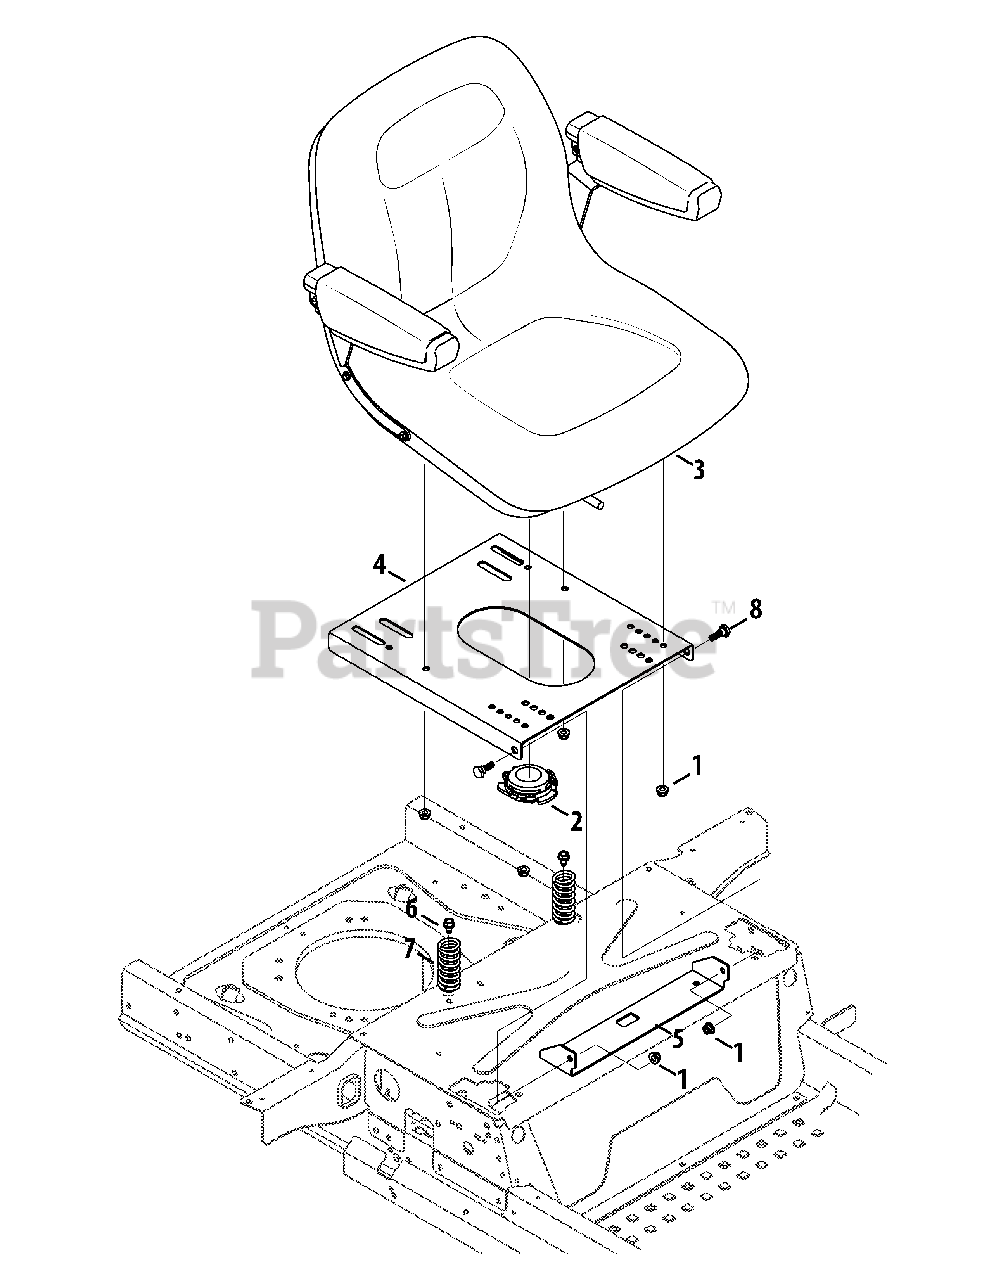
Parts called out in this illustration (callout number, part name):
1	Flange Lock Nut, 5/16-18
2	Seat Switch
4	Seat Plate
6	Hex Washer Screw, 5/16-18 x .750
7	Compression Spring, 1.71 x 3.25 x .23
8	Shoulder Screw, 5/16-18 x .437 x .268
